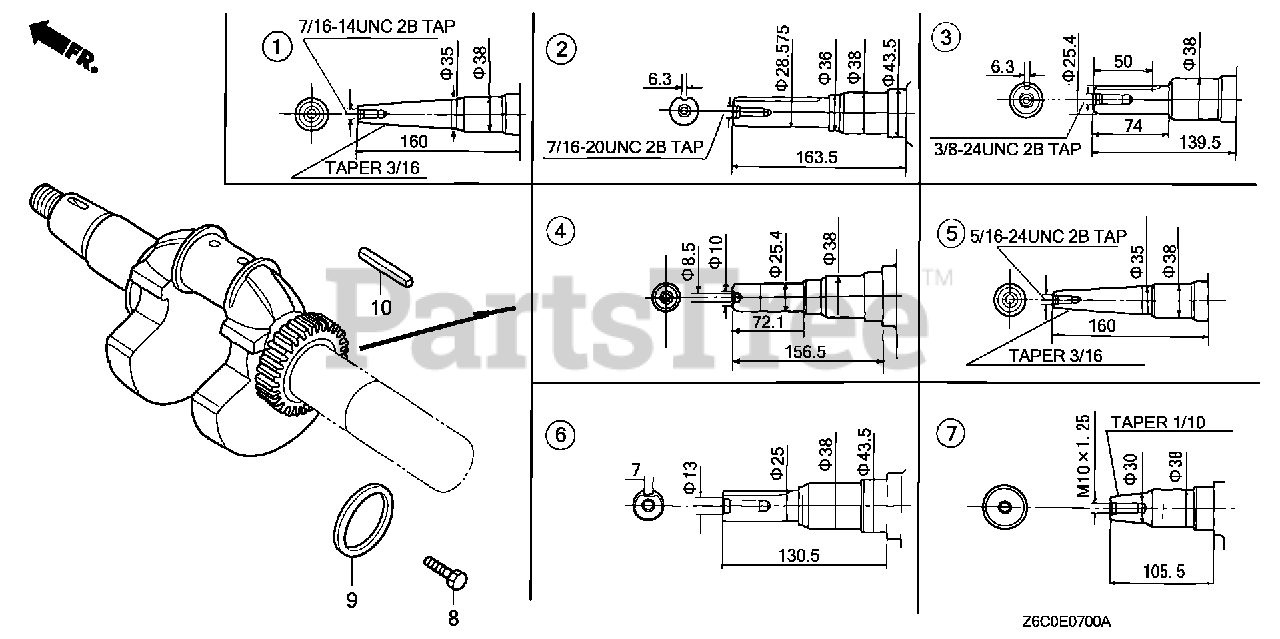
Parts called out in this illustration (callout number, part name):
3	CRANKSHAFT (L=139.5)
9	WASHER, CRANKSHAFT THRUST (38.5X54.0X1.0)
10	KEY (6.3X6.3X43)
